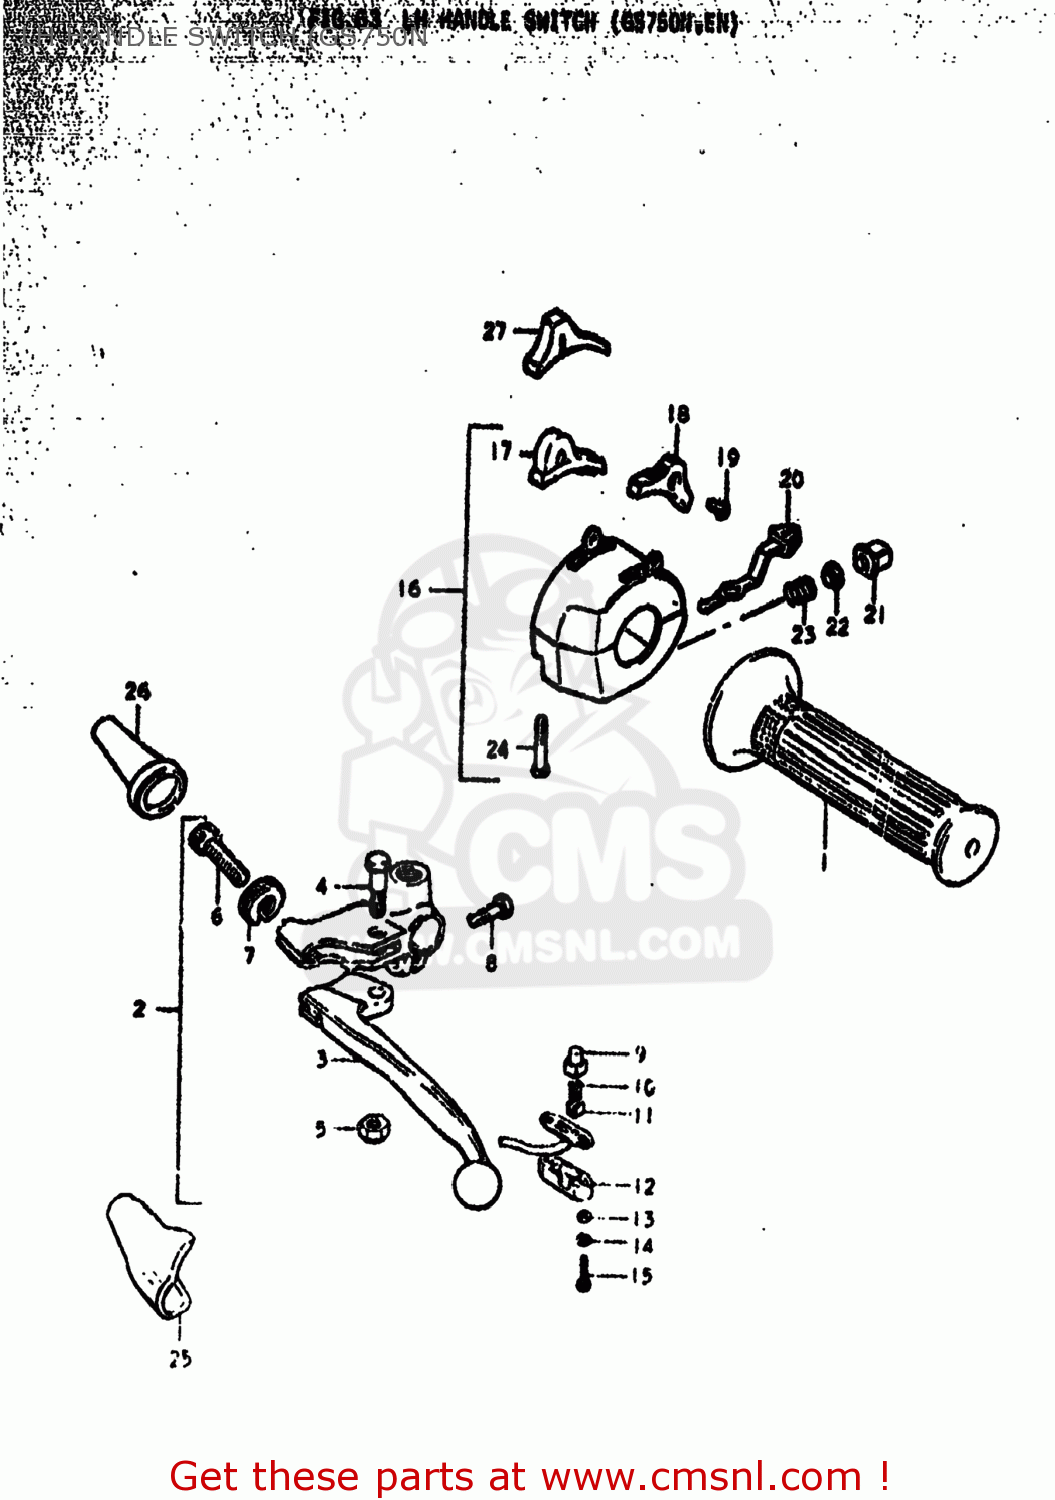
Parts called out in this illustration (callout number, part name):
1	GRIP,LEFT
2	LEVER ASSEMBLY
3	LEVER,CLUTCH
4	BOLT,LEVER
5	NUT 6MM
6	ADJUSTER,CABLE
7	NUT,CABLE ADJUSTER
8	BOLT
9	HOLDER
10	SPRING
11	PLATE
12	COVER,FR BK TERMINAL BASE
13	WASHER
14	LOCK WASHER
15	SCREW
16	SWITCH ASSEMBLY,HANDLE,LEFT
17	KNOB,STOP
18	KNOB,DIMMER SWITCH
19	SCREW
20	KNOB,TURNSIGNAL
21	BUTTON,HORN
22	CONTACT
23	SPRING
24	SCREW
25	COVER,CLUTCH LEVER
26	BOOT,CLUTCH CABLE
27	KNOB,LIGHTING SWITCH
